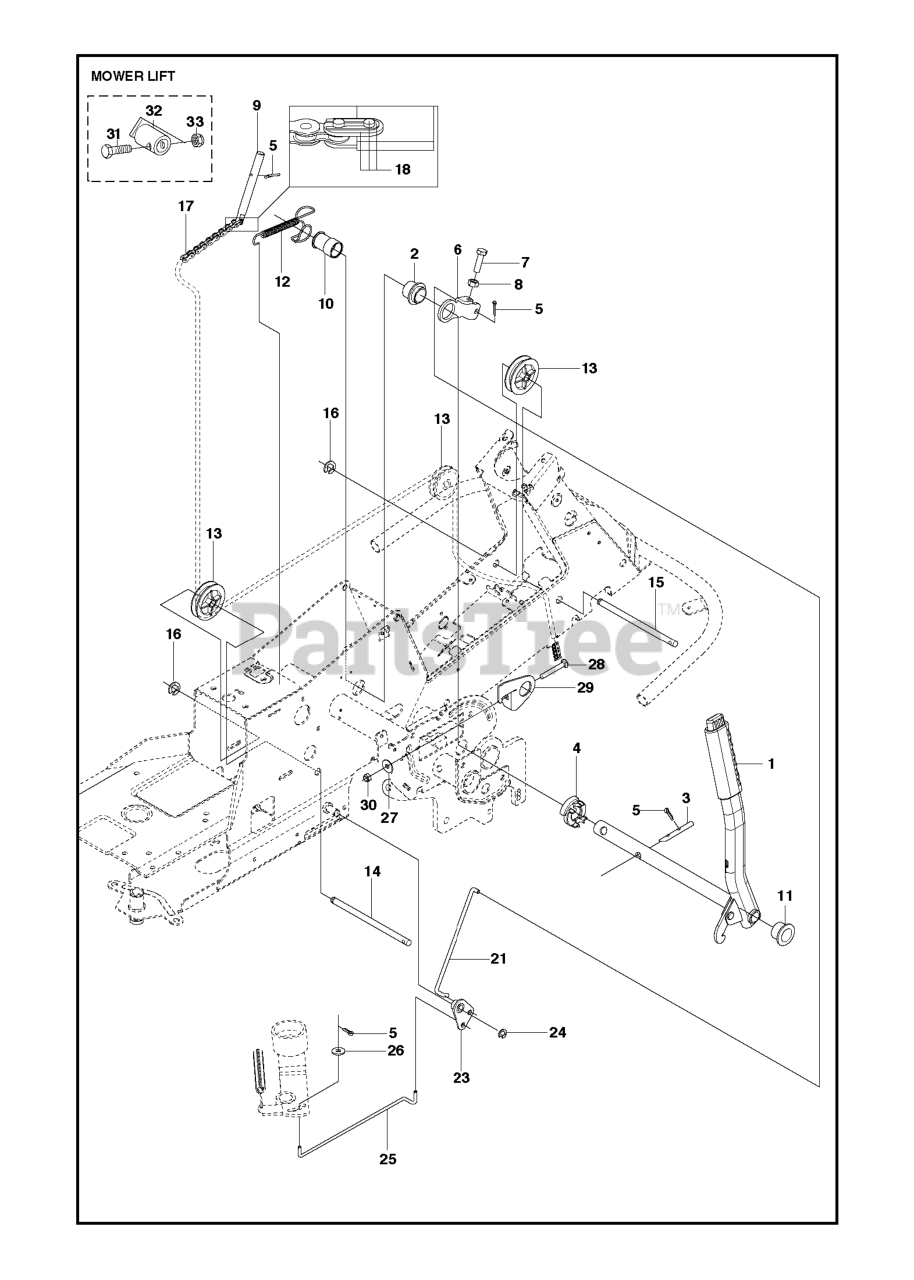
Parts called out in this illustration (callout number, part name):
6	LIFTING ARM LINK
11	BEARING FLANGE
21	CONNECTION ROD
24	RETAINING RING
25	CONNECTION ROD
